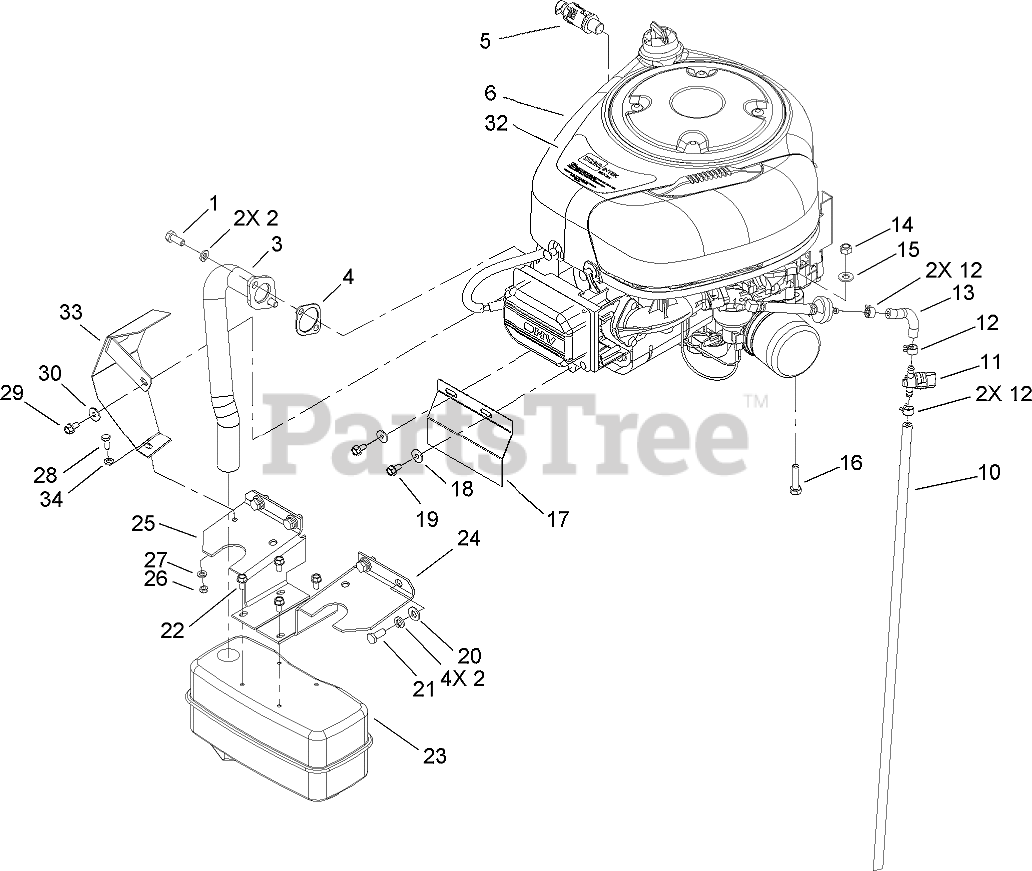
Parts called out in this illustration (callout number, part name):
1	SCREW-HH
2	WASHER-LOCK, SPRING
3	TUBE-EXHAUST
4	GASKET-EXHAUST
5	VALVE-OIL DRAIN
10	LINE-FUEL
11	VALVE-TANK, FUEL
12	CLAMP-LINE, FUEL
13	LINE-FUEL
14	NUT-LOCK, NI
15	WASHER-PLAIN
16	SCREW-HH
17	COVER-FRONT
18	WASHER-FLAT
20	WASHER-PLAIN
21	SCREW-HH
23	MUFFLER
24	GUARD-MUFFLER, LH
25	GUARD-MUFFLER, RH
26	NUT-HEX
27	WASHER-SPRING
28	SCREW-HH
30	WASHER-FLAT
32	DECAL-ENGINE
33	Cover-Manifold, Exhaust
34	WASHER-FLAT
